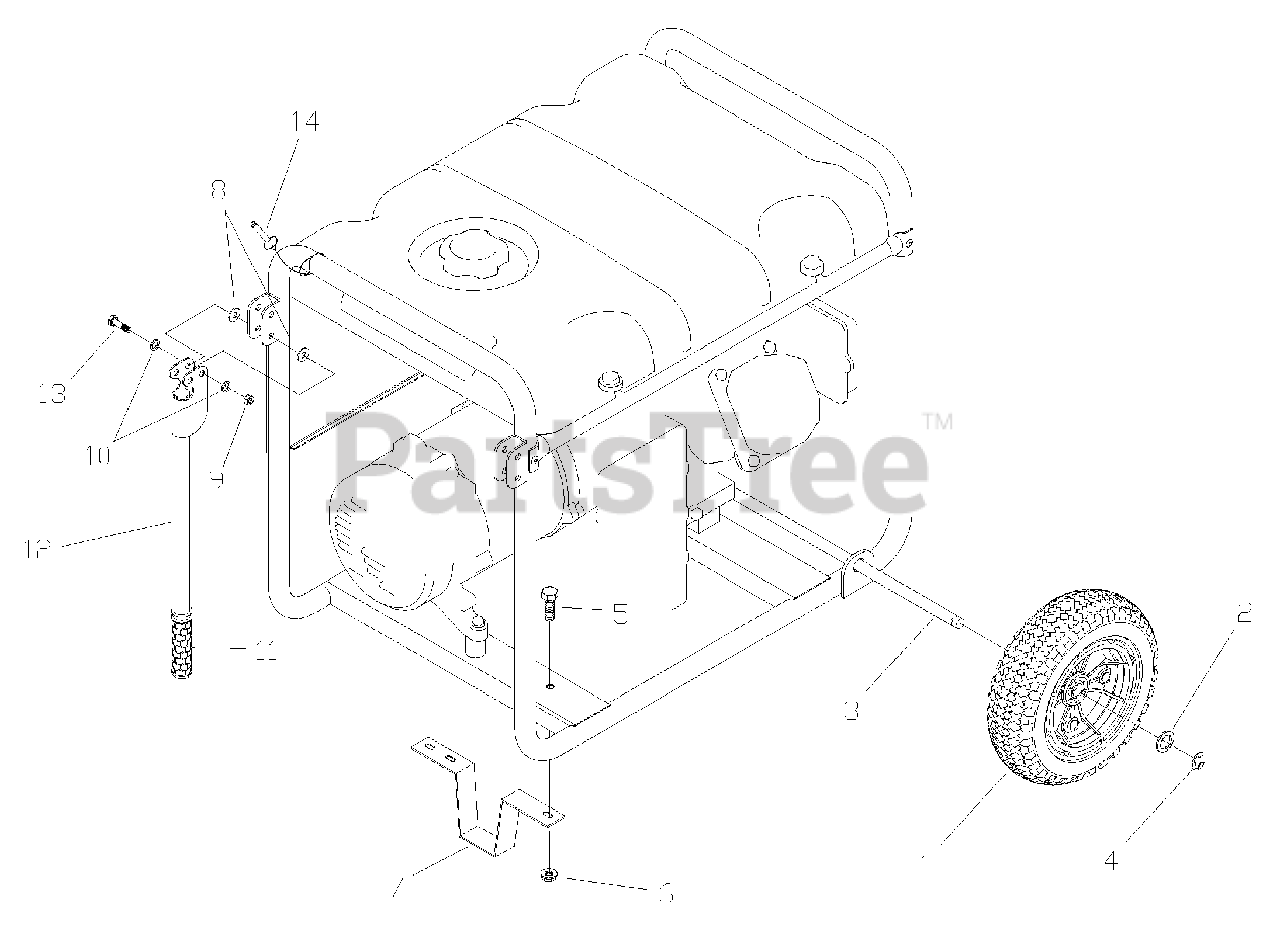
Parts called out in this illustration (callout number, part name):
2	*WASHER, 5/8
3	AXLE
4	E-RING
5	*CAPSCREW, Hex Head, M8 - 1.25 x 20
6	NUT, Flange Serrated, M8
8	WASHER, 1.2 x .346 x .03, Nylon
9	*NUT, Nylok, M8 x 1-1/4
10	*WASHER, Flat, 5/16 - M8
12	HANDLE
13	*CAPSCREW, Hex Head, M8 - 1.25 x 45
